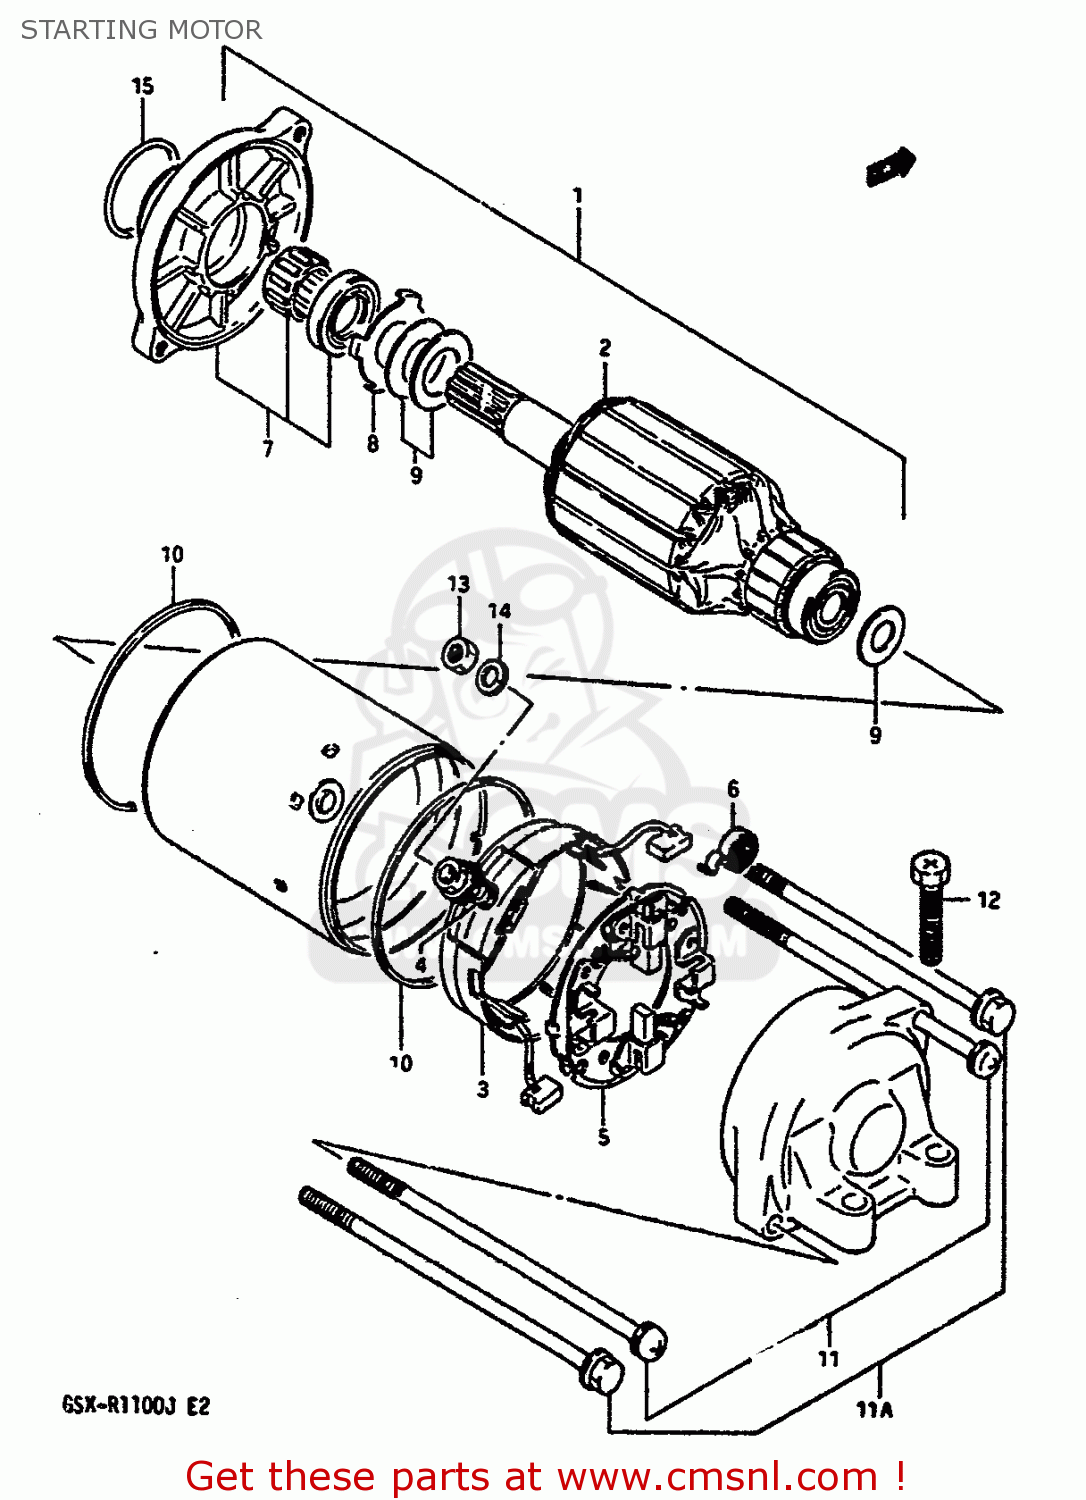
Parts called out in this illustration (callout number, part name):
1	MOTOR ASSY,STARTING
2	ARMATURE
3	TERMINAL SET,BRUSH,PLUS
4	O RING
5	HOLDER SET,BRUSH(-)
6	SPRING,BRUSH
7	BRACKET SET,STARTING MOTOR
8	SHIM SET
9	SHIM SET
10	SEAL,RING
11	BOLT
11A	BOLT SET
12	SCREW (6X25)
13	NUT
14	WASHER,LOCK
15	O RING(D:3,ID:24.5)
